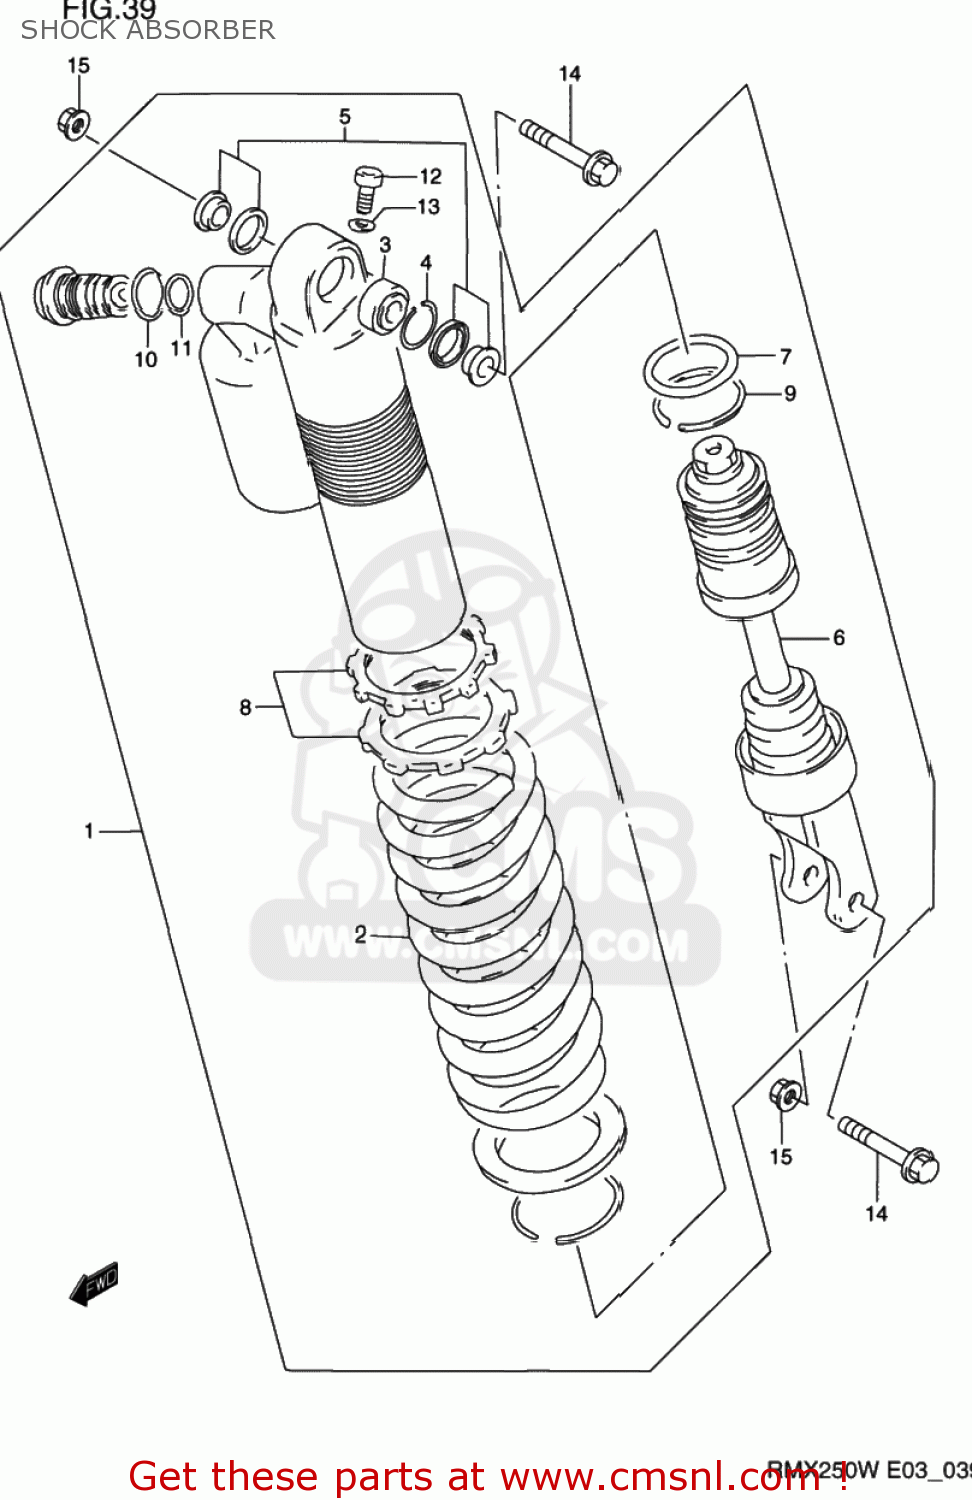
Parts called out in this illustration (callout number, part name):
1	ABSORBER ASSEMBLY,REAR SHOCK
2	SPRING
3	BEARING,RR CUSHION LEVER RR
4	RING,STOPPER
5	COLLAR SET,RR SHOCK ABSORBER
6	ROD,PISTON
7	O RING
8	ADJUSTER SET,SHOCK ABSORBER
9	RING,STOPPER
10	O RING
11	O-RING,FORK BOLT,LOWER
12	BOLT
13	GASKET,DRAIN,PLUG (NAS)
14	BOLT,RR SHOCK ABSORBER
15	NUT
